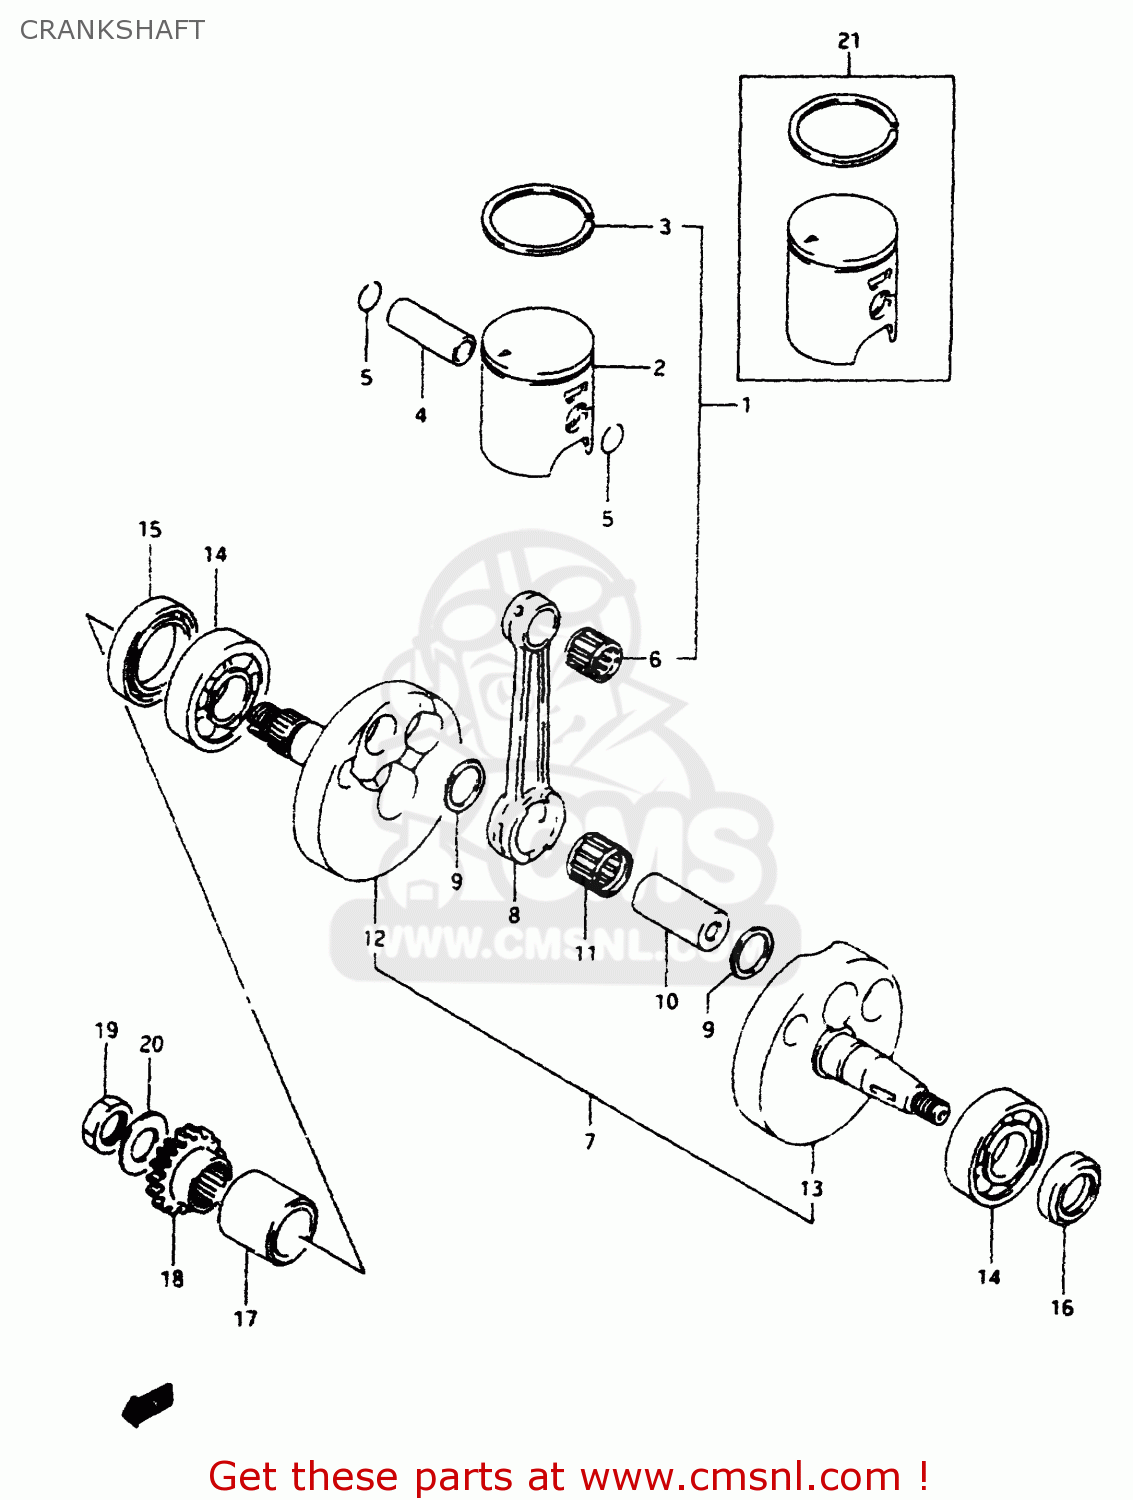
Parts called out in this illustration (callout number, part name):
1	PISTON
2	RING,PISTON
3	PIN,PISTON
4	RING,SNAP 14MM
5	BEARING(14X18X16)
6	CRANKSHAFT ASSY
7	ROD,CONNECTING
8	WASHER
9	PIN,CRANK
10	BEARING(20X26X13.7)
11	CRANKSHAFT,RIGHT
12	CRANKSHAFT,LEFT
13	BEARING(20X52X15)
14	SEAL,OIL(30X40X7)
15	SEAL,OIL(18X30X6)
16	SPACER,PRIMARY DRIVE GEAR
17	GEAR,PRIMARY DRIVE (NT:
18	NUT
19	WASHER
20	PISTON SET(OS:0.5)
21	TOP END KIT,ENGINE
22	PISTON KIT
23	RING,PISTON(OS:0.5)
